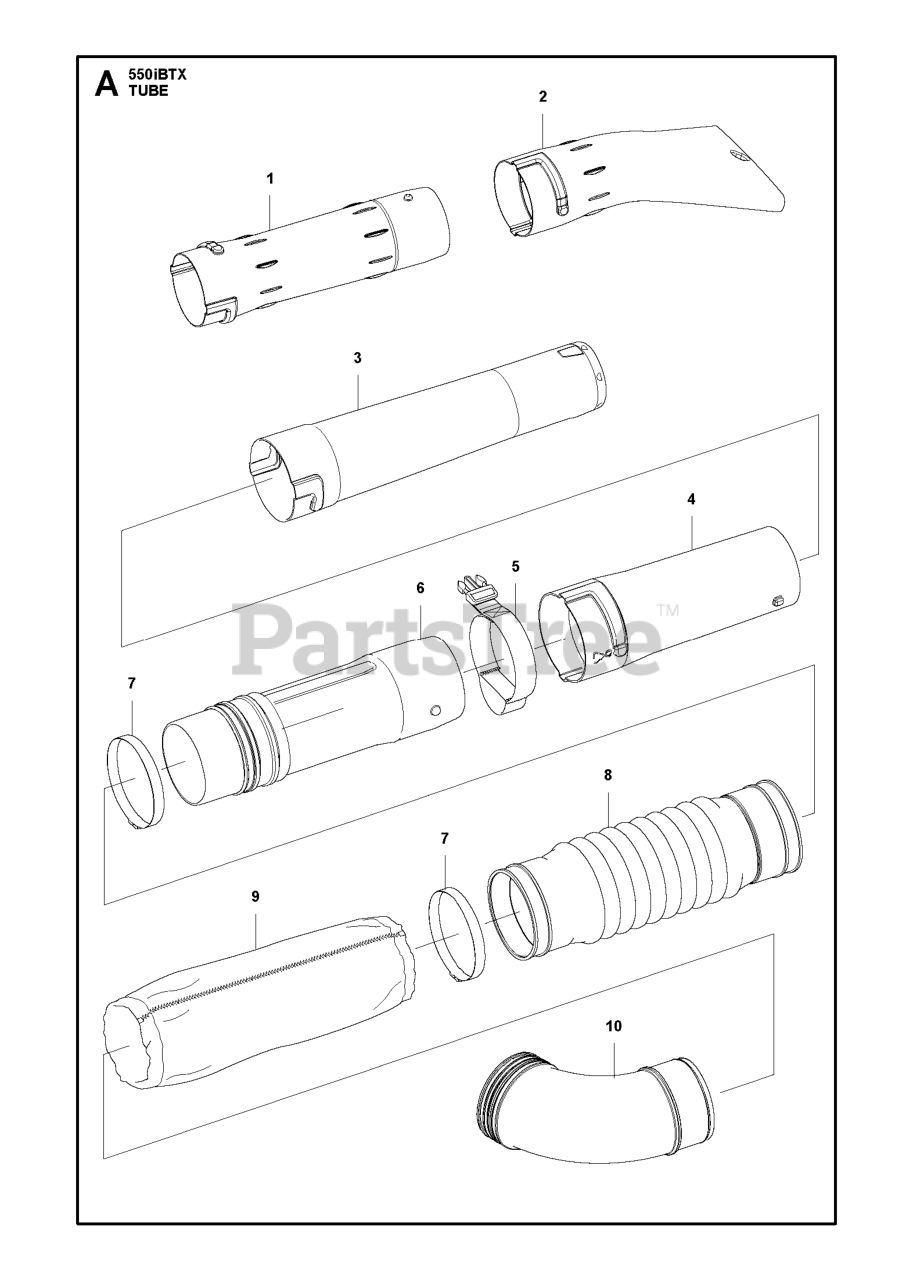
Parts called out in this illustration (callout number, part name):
1	PIPE STRAIGHT
2	NOZZLE FLAT
3	TUBE ASSY NOZZLE 536LIBX
4	TUBE ADAPTER PLASTIC HUSQVARNA
5	STRAP TUBE BLOWERS
6	SWIVEL JOINT
7	CLAMP(F115)
8	HOSE FLEXIBLE
9	SLEEVE TUBE
10	PIPE ELBOW
